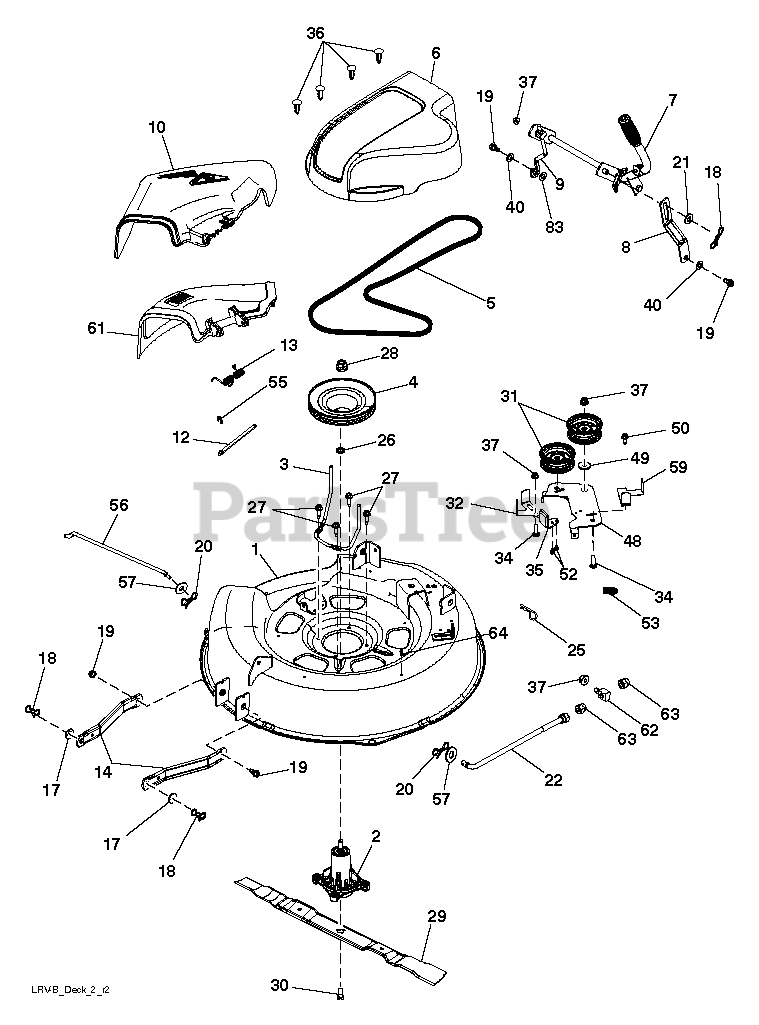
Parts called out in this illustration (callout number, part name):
1	DECK.WELDMENT.LRV.30.BLACK
2	MANDREL.ASM.SUB-NON.GR
3	KEEPER.LRV.GEN2.MANDREL BELT
4	PULLEY.LRV.GENS.MANDREL
5	V-BELT.MOWER.30.LRVB
6	COVER.MANDREL.30".LRV.(B)
7	LIFT.ASM.DECK.LRV
8	LINK, DECK LIFT
9	LINK.ASM.LIFT.ADJUSTABLE
12	ROD.HINGE
13	SPRING.TORSION.DEFLECT
14	ARM.SUSPENSION.MOWER
17	WASHER.CLEAR.ZINC
18	PIN.COTTER.7/16.BOW TI.
19	BOLT.SHOULDER
20	PIN.COTTER.5/16.BOW TI
22	SUBASM.LINK.DECK.TOP.LRVB
26	WASHER.SPACER.MANDREL
27	SCREW, WASHER HEAD
28	NUT.FLANGE.LOCK.TOP
29	BLADE, MULCH.LRV30
30	BOLT.WASHER.ASM.7/16-2
31	PULLEY.IDLER.48"PRIMARY
32	GUARD, BELT
34	BOLT.3/8-16X1.50
35	ARM BRAKE MOWER RH
36	SCREW.1/4-20X5/8
37	NUT LOCK FLG 3/8-16 UNC
48	ARM.LRV.GEN2.CLUTCHING
49	SPACER.RETAINER
50	SCREW 3/8-16X1
52	SCREW 1/4X20
53	SPRING RETURN
55	E-RING.5/16"
56	ROD.LRV.GEN2.ANTI.SWAY
57	WASHER
59	GUARD.TUV.IDLER.42
61	MULCH.COVER.ASSEMBLY.30"
62	TRUNNION
63	NUT, LIFT LINK 7/16-20
64	SCREW 3/8-16X1/2
83	WASHER
